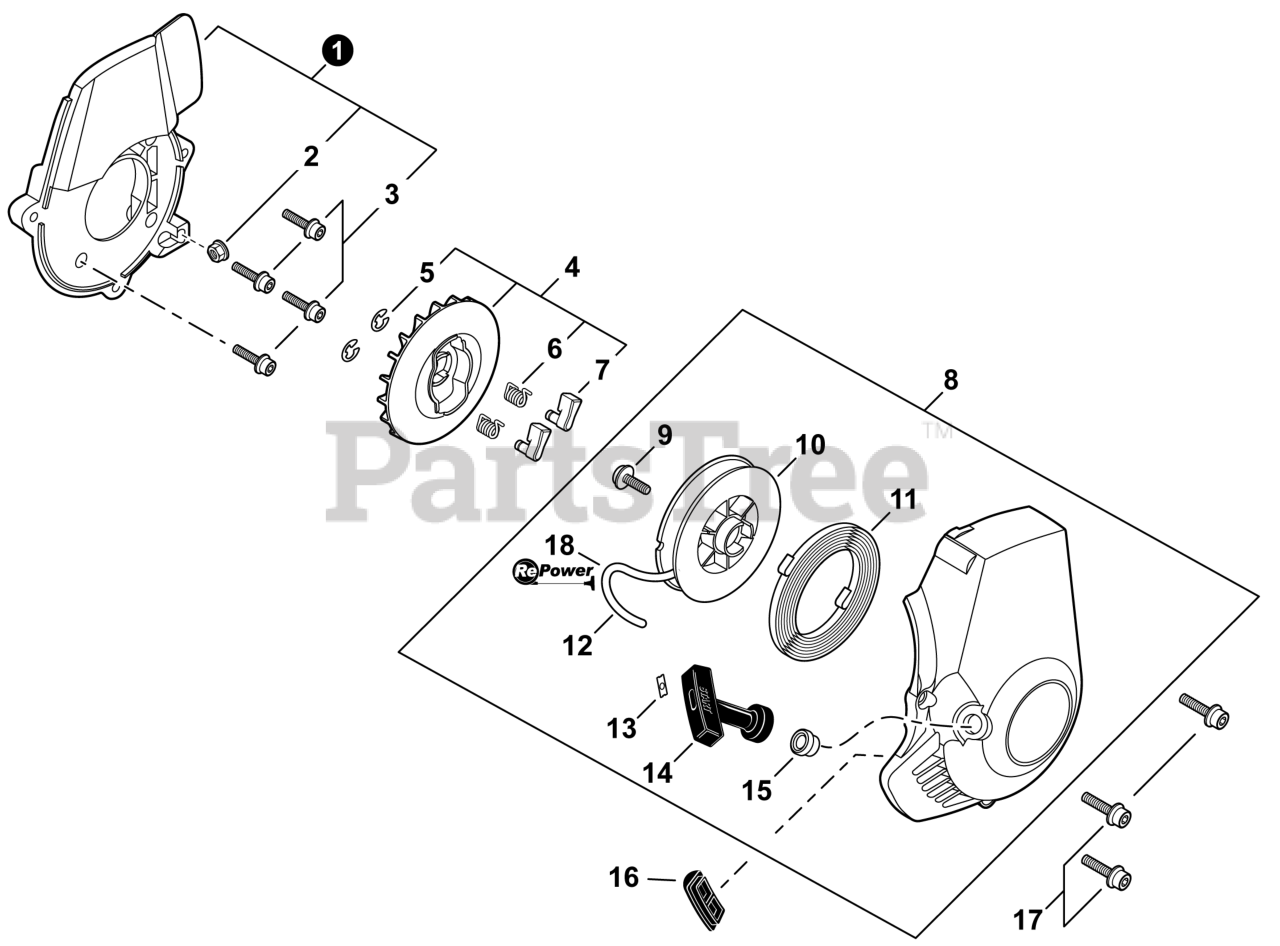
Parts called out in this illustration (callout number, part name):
1	SPACER ASSY.
2	NUT, FLANGE M5
3	BOLT 4×16
4	PAWL ASSY, STARTER
5	E-RING 4
6	SPRING, RETURN
7	PAWL, STARTER
8	STARTER ASSY, RECOIL
10	REEL, ROPE
11	SPRING, RECOIL
12	ROPE, STARTER 3×700
13	CLIP, STARTER ROPE
14	GRIP, STARTER
15	GUIDE, ROPE
16	CUSHION
17	BOLT 5×14
18	BULK STARTER ROPE - Ø 3.0 MM×61 M
